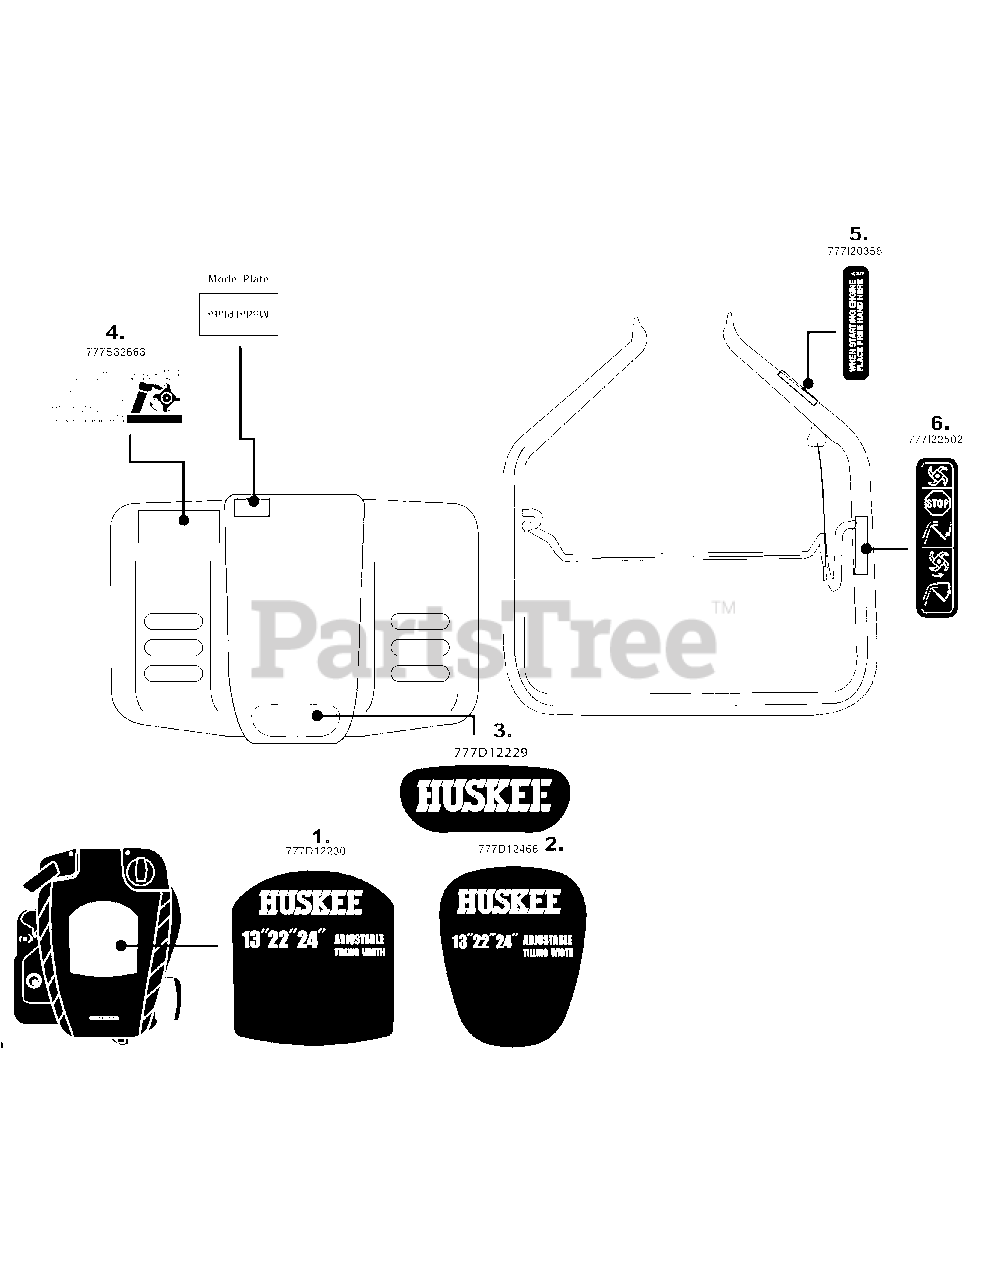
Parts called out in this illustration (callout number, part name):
1	LABEL-TILLER SHROUD HUSKEE
2	LABEL-TILLER SHROUD HUSKEE
3	LABEL-TILLER TINE SHIELD HUSKEE
4	LABEL-TILLER TINE SHIELD:WARNIN
5	LABEL-PLACE HAND HERE
6	LABEL:TILLER HANDLE:ENGAGE
